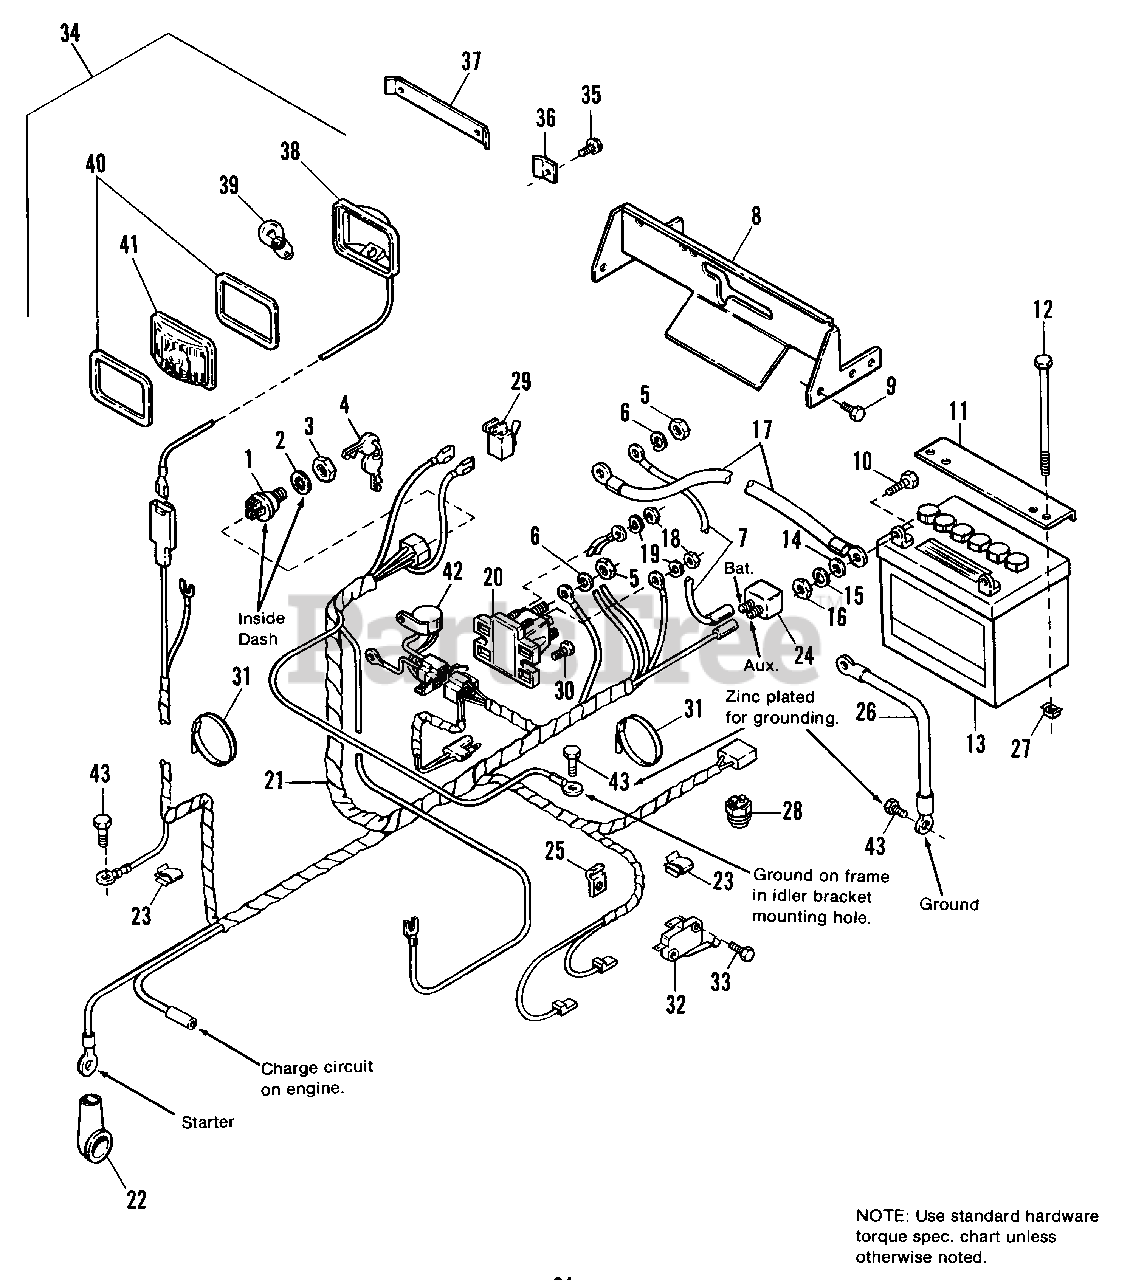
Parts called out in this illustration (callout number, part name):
1	SWITCH, Ignition (Incl. Ref. No. 2, 3,& 4)
2	LOCKWASHER, Internal Tooth, 5/8
3	NUT, 5/8-32
5	NUT, Hex, 5/16-24
6	LOCKWASHER, 5/16
8	QUADRANT, Shift
9	SCREW, Taptite, 1/4-20 x 3/8
10	CAPSCREW, Hex, 1/4-20 x 3/4
11	CLAMP, Battery
12	CAPSCREW, Hex, 1/4-20 x 7
13	BATTERY SERVICE KIT
14	WASHER, 1/4
15	LOCKWASHER, 1/4
16	NUT, Hex, 1/4-20
18	NUT, Hex, #10-32
19	LOCKWASHER, Ext., #10
20	SOLENOID
21	HARNESS, Wiring (11 HP)
21	HARNESS, Wiring (12 HP)
22	COVER, Terminal
23	CLIP, Speed
24	CIRCUIT BREAKER
25	CLIP, Wire
27	NUT, Retainer, 1/4-20
28	SWITCH, PTO
30	SCREW, Taptite, 1/4-20 x 3/4
32	SWITCH, Interlock
33	SCREW, Taptite, #5-40 x 3/4
34	LIGHT ASSY.
35	SCREW, Plastite, #10-14 x 1/2
36	CLIP, Headlight, Side
37	CLIP, Headlight, Center
38	REFLECTOR ASSY.
41	LENS, Plastic, Clear
42	MODULE-DIS INTERLOCK
43	SCREW, Taptite, 1/4-20 x 3/8, Zinc Pltd.
